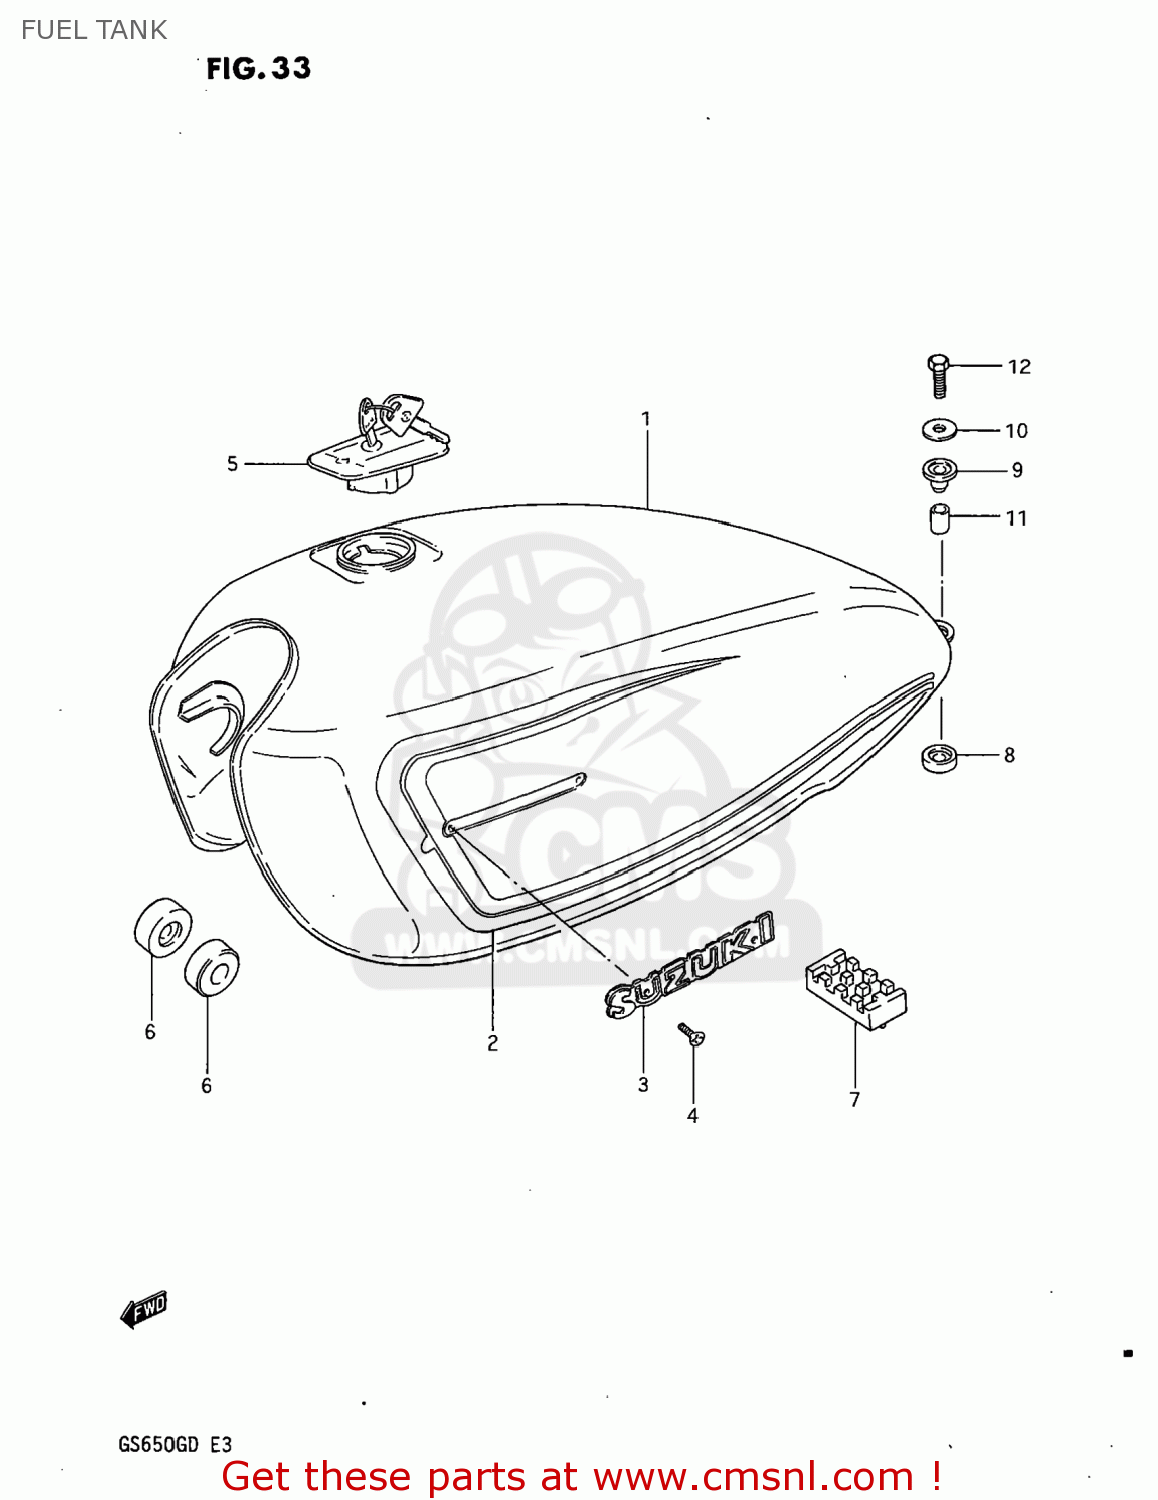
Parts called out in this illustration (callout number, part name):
1	TANK ASSEMBLY,FUEL
2	TAPE SET,FUEL TANK
3	EMBLEM
4	SCREW 3X6
5	CAP SET,FUEL TANK
6	CUSHION
7	CUSHION,FUEL TANK CTR
8	CUSHION
9	CUSHION
10	WASHER (6.5X24X1.6)
11	SPACER
12	BOLT
